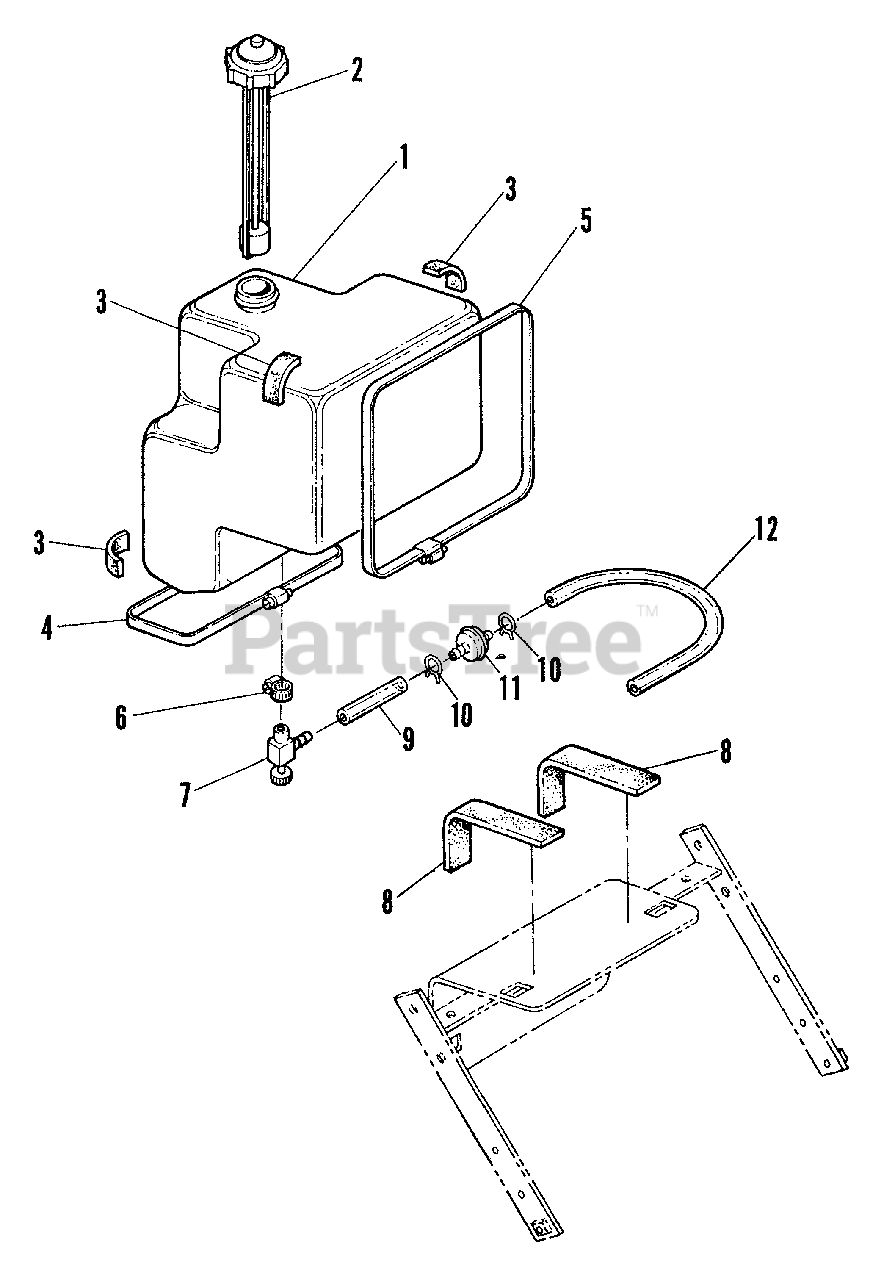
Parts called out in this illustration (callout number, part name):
1	TANK, Fuel w/Valve & Clamp
2	CAP, Fuel w/Gauge
3	PAD, Fuel Tank
4	BAND, Fuel Tank (Short)
5	BAND, Fuel Tank (Long)
6	CLAMP, Fuel Tank Valve
7	VALVE, Fuel Shut-Off
8	PAD, Fuel Tank Saddle
9	LINE, Fuel 3-1/2"
10	CLAMP, Fuel Line
11	FILTER, Fuel
12	LINE, Fuel 16" (Kawasaki)
